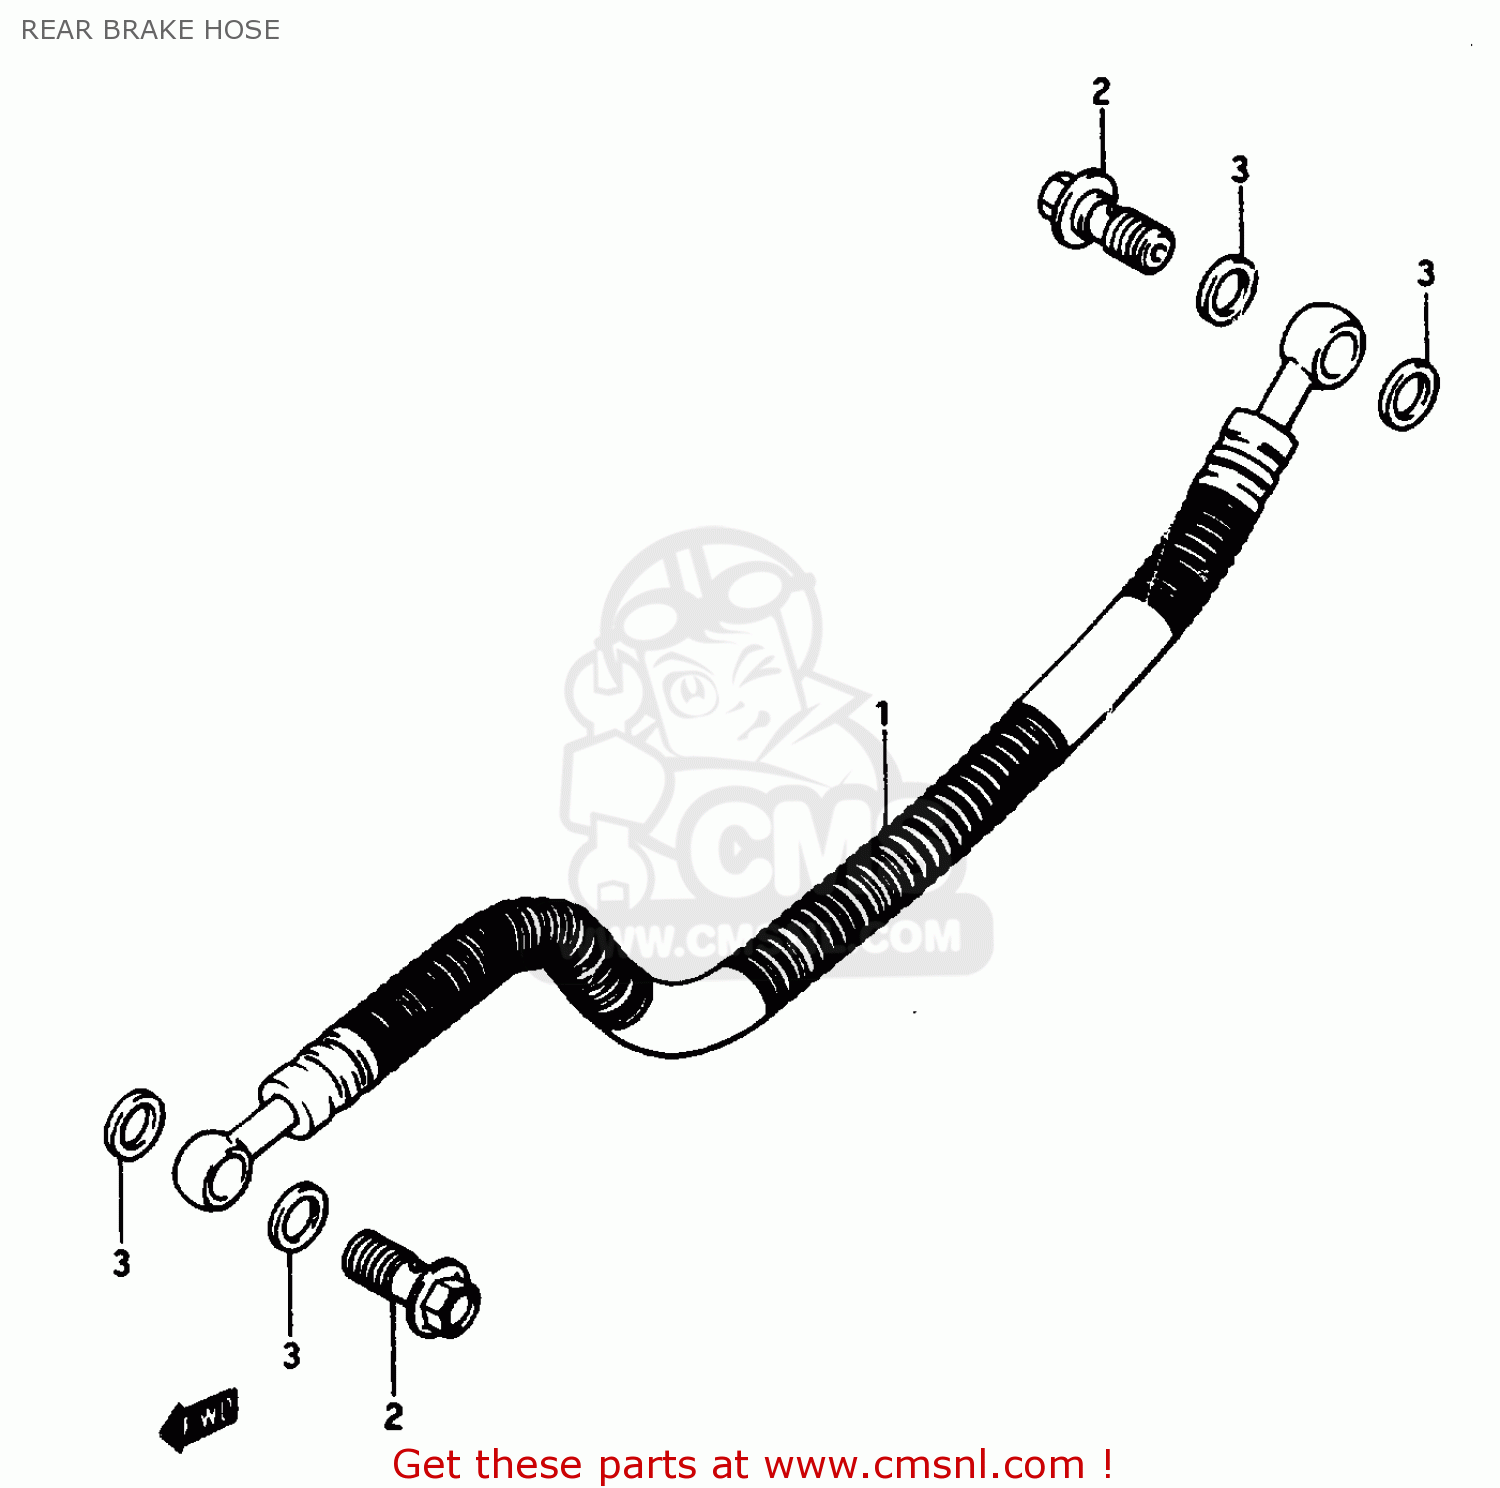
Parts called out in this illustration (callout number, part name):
1	HOSE,REAR BRAKE
2	BOLT UNION
3	WASHER(10X15X1.5)
